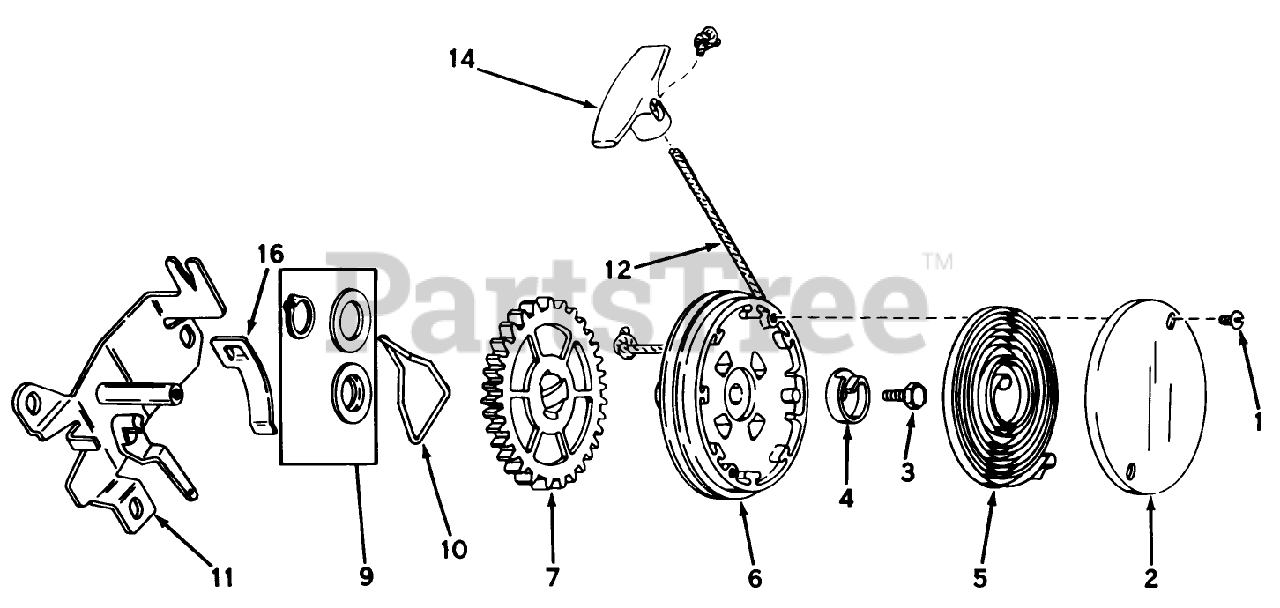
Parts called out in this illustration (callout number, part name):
1	Screw
2	Cover, Spring
3	Screw, Hex Washer Head
4	Hub Spring
5	Spring, Rewind
6	Pulley Assy. (Incl. No. 9)
9	Kit, Thrust Wash. Snap Rg.
10	Brake
11	Bracket Assy., Mounting
12	Rope-Starter
14	Handle-Starter
16	Clip Rope
